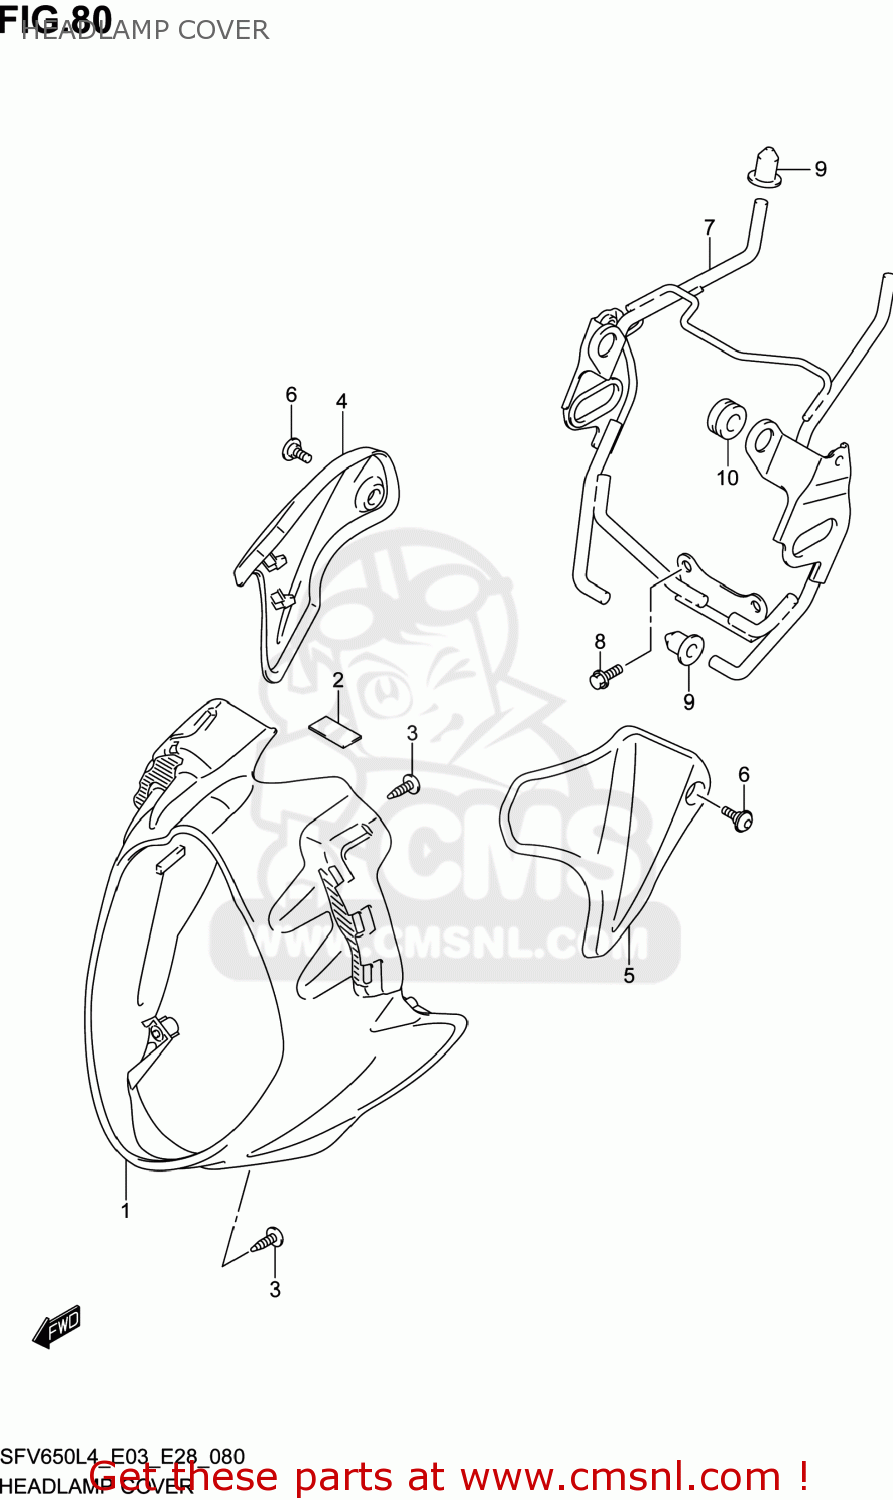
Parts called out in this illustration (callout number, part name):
1	COVER,HEADLAMP
2	CUSHION,FUEL TANK NO.2
3	SCREW
4	COVER,HEADLAMP,R
5	COVER,HEADLAMP,L
6	SCREW(5X13)
7	BRACE,HEADLAMP HOUSING
8	BOLT
9	CUSHION,HEADLAMP HOUSING BRACE
10	CUSHION
